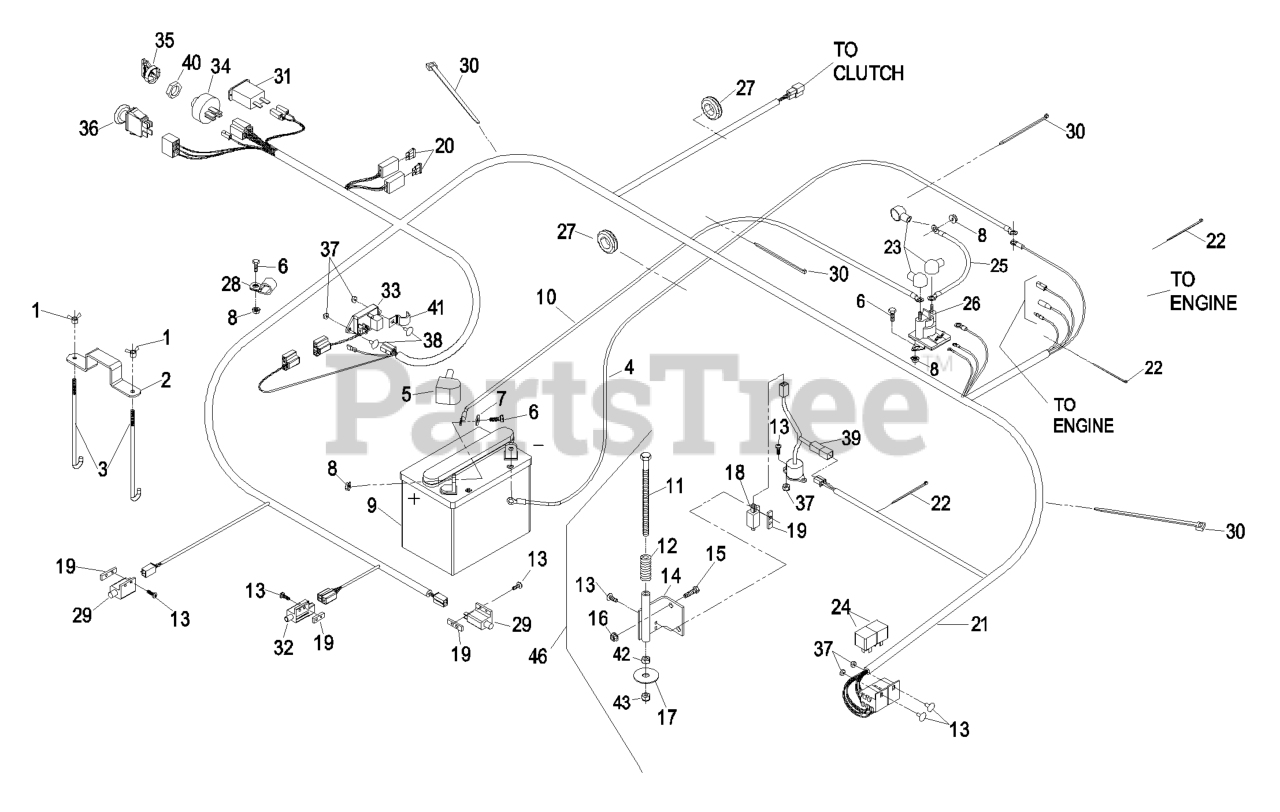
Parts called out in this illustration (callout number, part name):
1	WINGNUT
2	STRAP-HOLDDOWN
3	BOLT-HOLDDOWN
4	CABLE-GROUND, NEGATIVE
6	SCREW-HH
7	WASHER-FLAT
11	SCREW-HH
12	SPRING-SWITCH, SEAT
13	SCREW-PPH
14	BRACKET-SWITCH, SEAT
15	SCREW-HH
18	SWITCH-CLOSED, NORMALLY
19	PLATE-TAPPED
20	FUSE-BLADE TYPE, 20 AMP
22	TIE-CABLE
23	INSULATOR-SOLENOID
27	GROMMET
28	CLIP-LOOM
29	SWITCH-OPEN, NORMALLY
30	TIE-PLASTIC
31	METER-HOUR
33	MODULE-DELAY, SEAT
35	KEY-IGNITION
36	SWITCH-PTO
37	NUT-LOCK, NI
38	SCREW-HEAD, TRUSS
40	NUT-SWITCH, IGNITION
41	BOLT-CARR
42	WASHER-FLAT
43	CLIP-HALF, LOOM
44	NUT-HEX
45	NUT-LOCK, NI
46	ASM,SEAT SWITCH ACTUATOR
